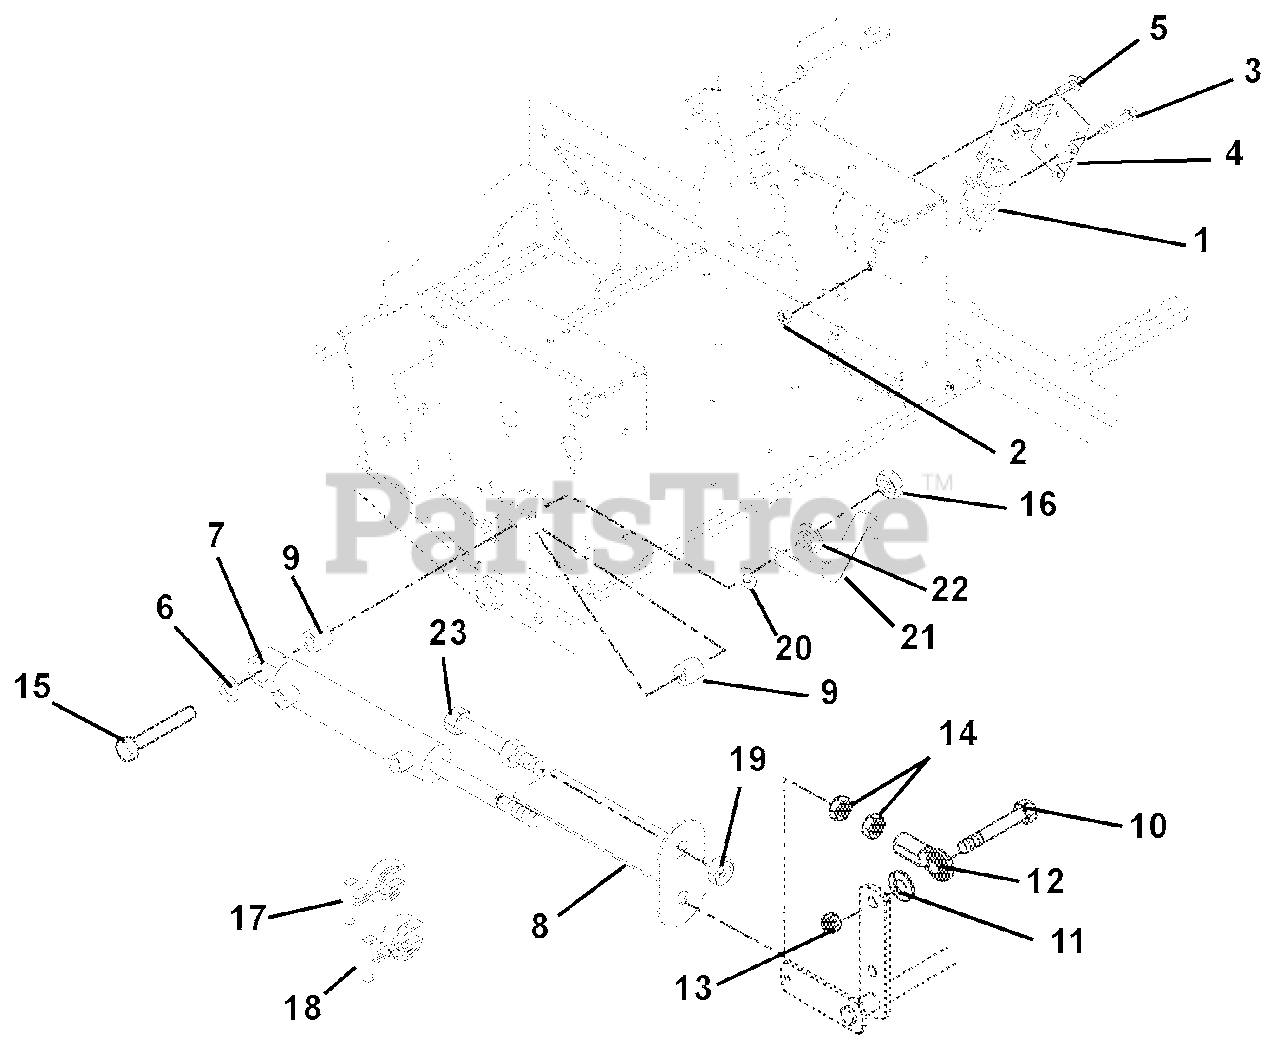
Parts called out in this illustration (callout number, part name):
1	Valve, Hydraulic
2	Nut, Locking Top Flange .31-18
3	Bolt, Hex .31-18 x 2.50 Grade 5
4	Bracket, Valve Mounting
5	Screw-Tapping .38-16 x .50 Hex Washer Head
6	Washer-Flat-Steel .515 x 1.625 x .25
7	Cylinder-Lift
8	Strap-Height of Cut Indicator
9	Bushing .516 x 1.00 x 1.05
10	Bolt-Hex .62-11 x 2.25 Grade 8
11	Washer-Lock .62 x .156
12	Rod End-Right Hand-Female .625
13	Nut-Locking-Center .62-11
14	Nut-Jam .625-18
15	Bolt-Hex .50-13 x 3.75 Grade 5
16	Nut, Locking Top Flange .50-13
17	Stop, Cylinder .34 Thick
18	Stop, Cylinder .68 Thick
19	Nut, Jam .75-16
20	Washer, Wave .076 x 1.12 x .08
21	Latch, Floor Board
22	Bushing-Flange .515 x .75 x .275 x 1.12
